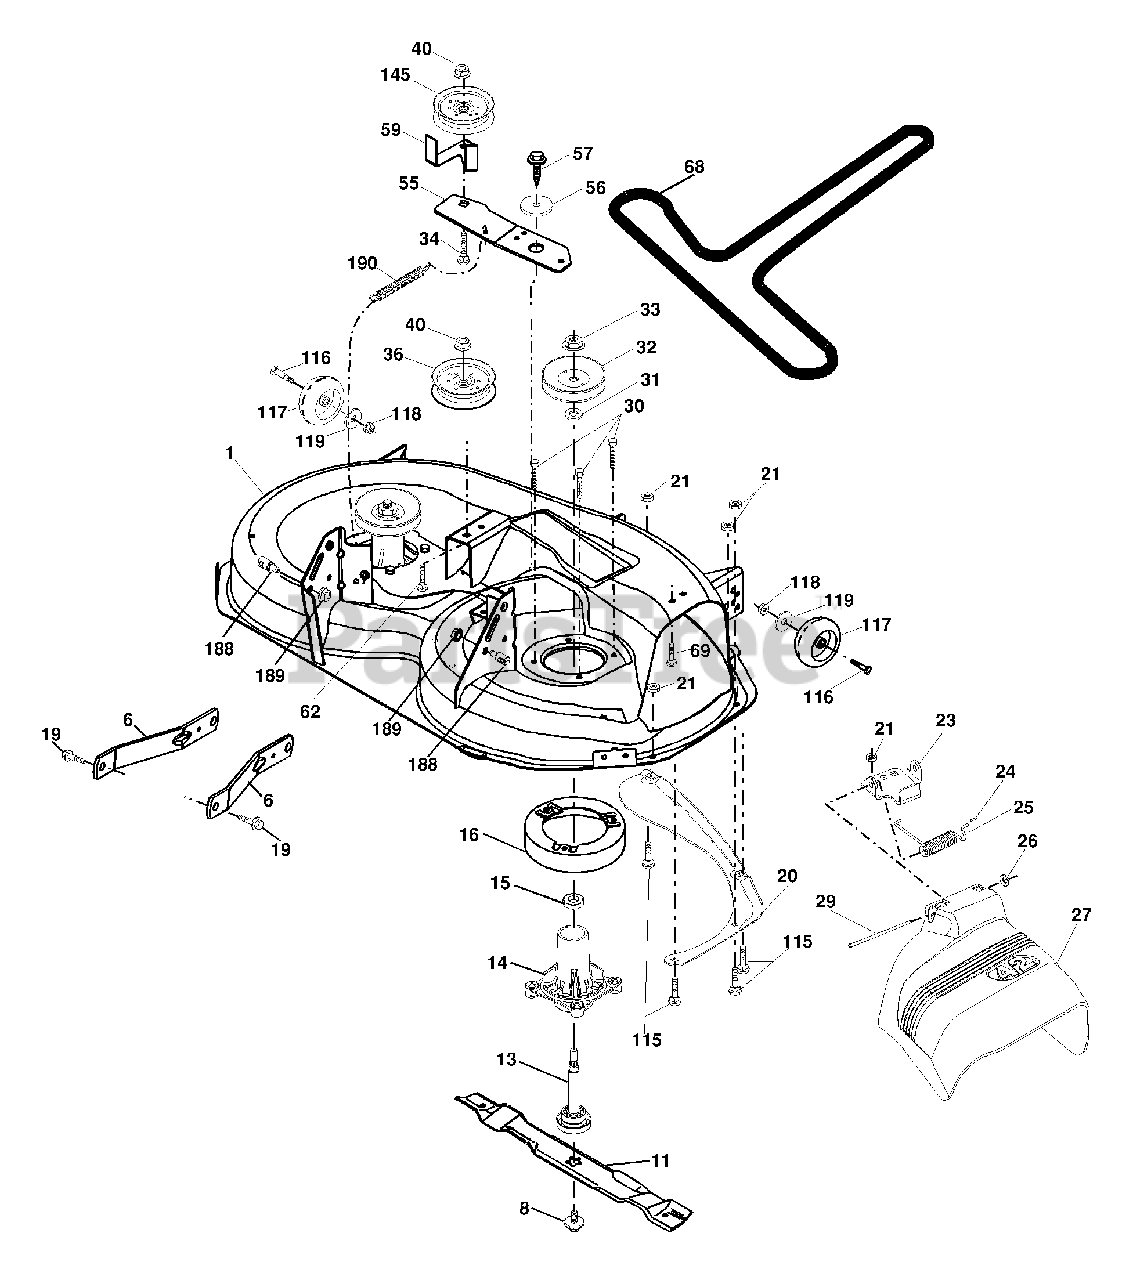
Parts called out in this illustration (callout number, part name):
1	Mower Housing
6	Arm Suspension
8	Bolt/Washer asm 7/16-20 unf
11	Blade, 42" Hi-Lift
11	Blade, 42" Mulching Std
11	Blade, 42" Mulching Premium
13	Shaft Assembly, Mandrel
14	Housing, Mandrel
15	Bearing, Ball, Mandrel
16	Stripper, Mower Deck
19	Bolt, Shoulder
20	Baffle, Vortex
21	Nut, Crownlock 5/16-18 unc
23	Bracket, Deflector
24	Cap, Sleeve
25	Spring, Torsion, Deflector
27	Shield, Deflector
29	Rod, Hinge
30	Screw Thdrol Rolling Wsh Hd
31	Washer, Spacer
32	Pulley, Mandrel
33	Nut, Toplock, Flanged
34	Bolt Carr Sh.
36	Pulley, Idler, Flat
40	Nut, Lock Flg. 3/8-16 unc
55	Arm, Idler
56	Spacer, Retainer
57	Screw 3/8-16 x 1
59	Guard, Tuv Idler
62	Bolt Rd Hd Sq Nk 3/8-16 unc x 2
69	Bolt
115	Bolt Carr. 5/16-18 x 5/8
116	Bolt, Shoulder
117	Wheel, Gauge
118	Nut, Crownlock 3/8-1
119	Washer 13/32 x 7/8 x 14 Ga.
145	Pulley Idler
188	Stud Fastener
189	Nut Lock Hex Flange
190	Spring Mower Drive Electric
